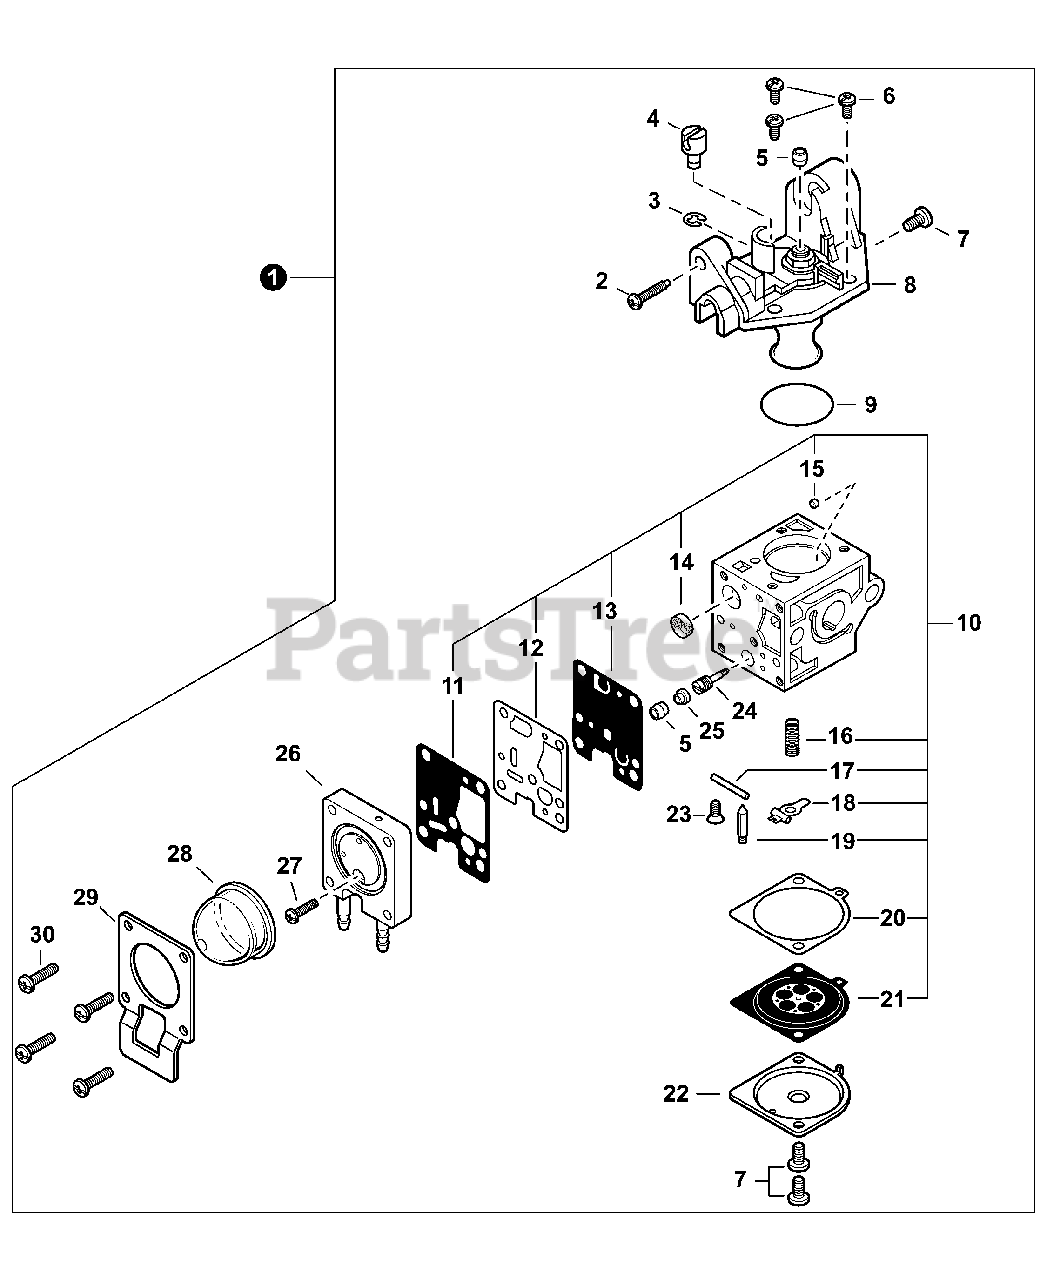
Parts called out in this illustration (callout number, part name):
1	CARBURETOR - RB-K99
2	SCREW, THROTTLE ADJUST
8	COVER ASSY, ROTOR
10	REPAIR KIT
11	DIAPHRAGM, SURGE
12	GASKET, PUMP
13	DIAPHRAGM, PUMP
14	SCREEN, FUEL INLET
15	GUIDE, ROLLER
16	SPRING, METERING LEVER
17	PIN, METERING LEVER
18	LEVER, METERING
19	VALVE, INLET NEEDLE
20	GASKET, METERING DIAPHRAGM
21	DIAPHRAGM, METERING
22	COVER, METERING DIAPHRAGM
24	NEEDLE, HIGH SPEED
25	CAP, LIMITER
26	BODY ASSY, PURGE
28	BULB, PURGE
29	RETAINER, PURGE BULB
